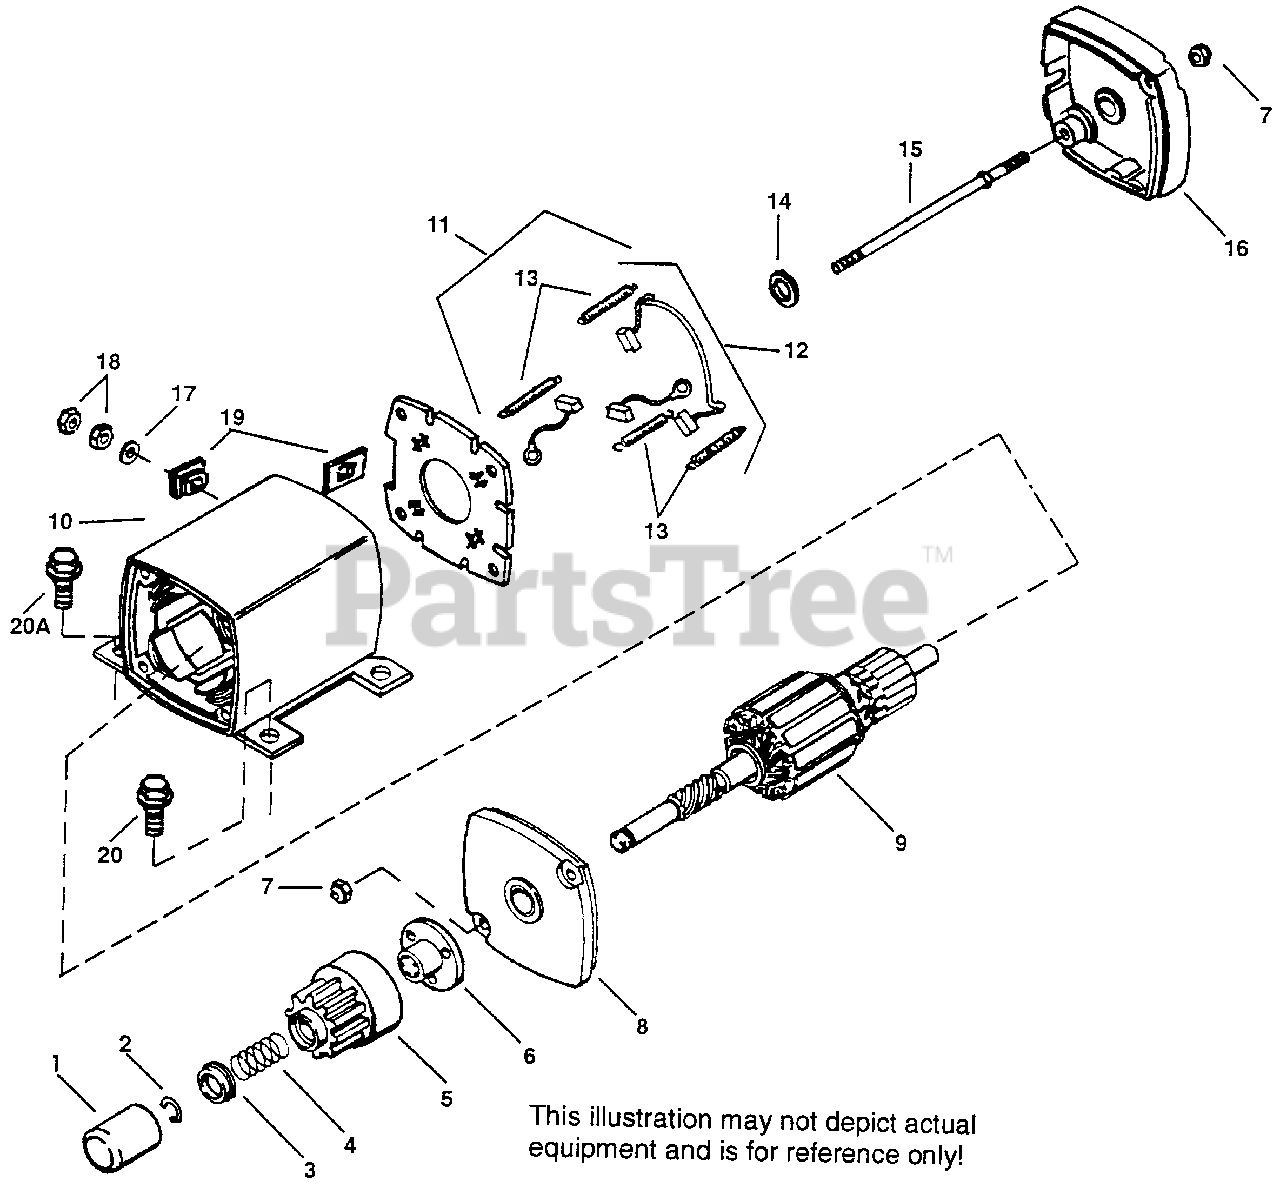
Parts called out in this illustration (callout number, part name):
1	Dust Cover
2	Retainer Ring
3	Spring Retainer
4	Anti-drift Spring
6	Nut & Retainer (Incl. 2)
7	Lock Nut
8	Drive End Cap Ass'y.
9	Armature
10	Housing Ass'y.
11	Brush Card Ass'y. (Incl. 12)
12	Brush & Spring Kit (Incl. (4) of 13)
13	Brush Spring
14	Thrust Washer
15	Bolt, 10-32 x 4-1/4"
16	Commutator End Cap Ass'y.
19	Terminal Insulaator
